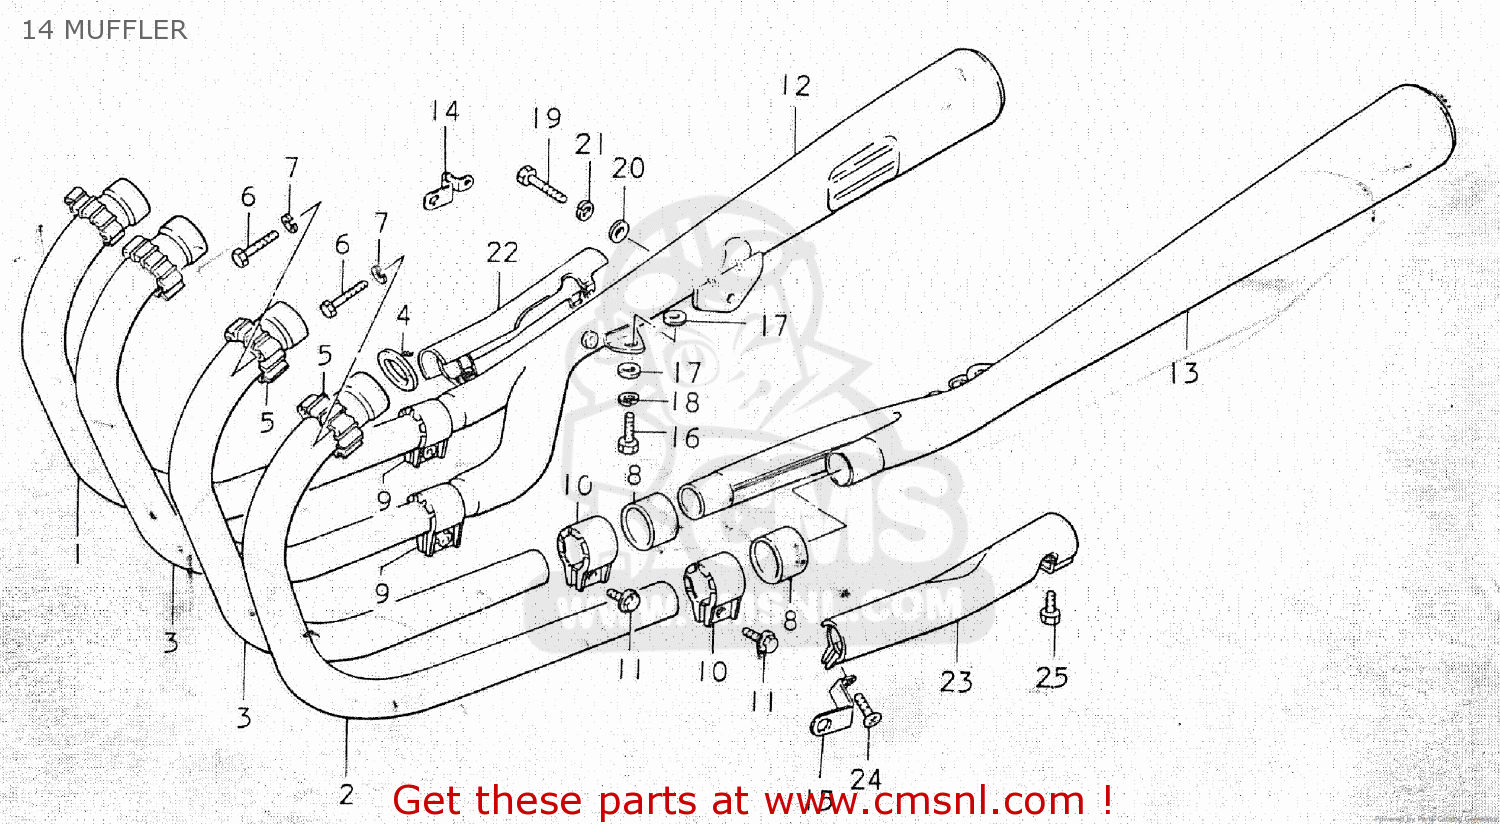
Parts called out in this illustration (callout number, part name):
1	PIPE,EXHAUST,RIGHT
2	PIPE,EXHAUST,LEFT
3	PIPE,EXHAUST CTR
4	GASKET,EXHAUST PIPE (NAS)
5	CLAMP,EXHAUST PIPE
6	BOLT
7	LOCK WASHER
8	CONNECTOR,MUFFLER
9	CLAMP
10	CLAMP
11	BOLT
12	BODY,MUFFLER
13	BODY,MUFFLER
14	PLATE, CONNECTOR RH
15	PLATE, CONNECTOR LH
16	BOLT
17	WASHER (8.2X20X1.6)
18	LOCK WASHER
19	BOLT 10X30
20	WASHER
21	LOCK WASHER
22	COVER,MUFFLER
23	COVER,MUFFLER
24	SCREW 5X20
25	SCREW
